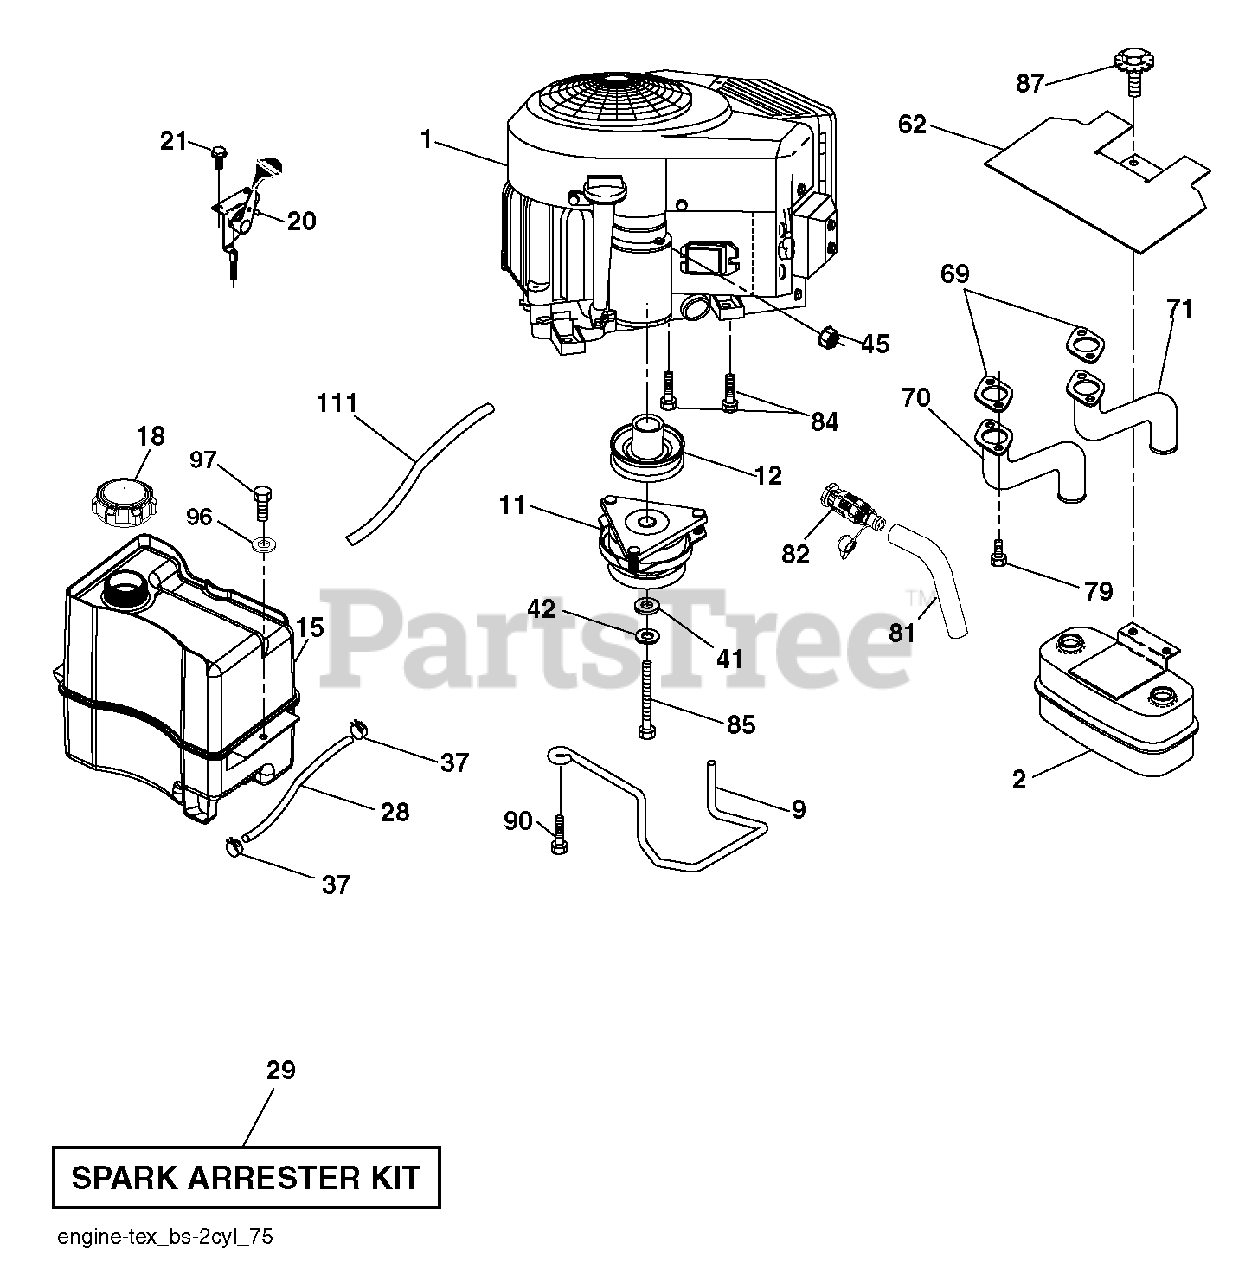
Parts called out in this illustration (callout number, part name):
2	MUFFLER.TWIN.CYL.LOW.TONE
9	KEEPER.BELT.ENGINE.3.25
11	CLUTCH.ELECTRIC.LT.48"*
12	PULLEY.ENGINE.ENX
15	TANK.ASM.FRT.2.5 GAL.W/CAP.EPA
18	CAP.FUEL.2 WAY VENT
20	CONTROL.TH/CK.COBRA.B&S.TWN.
21	SCREW.#10 X 0.750.BOS (2 2)
28	LINE.FUEL.20
29	SPARK ARRESTOR KIT
37	HOSE CLAMP
42	LOCKWASHER
45	NUT
62	SHIELD.HEAT.MUFFLER
69	GASKET.MUFFLER
70	EXHAUST.TUBE.LH.BS/TWIN
71	EXHAUST.TUBE.RH.B&S.TWIN.INTEK
79	SCREW.SOCKET.HEAD.5/16-18
81	TUBE, DRAIN OIL ASM.
82	VALUE.OIL.DRAIN
84	SCREW.3/8-16
85	BOLT HEX 7/16-20X4-1/4"
87	BOLT, 5/16-18 X 1 3/4
90	SCREW 3/8-16X1
97	SCREW HEXWSHR 1/4-20X3/4
111	RP PURGE LINE
